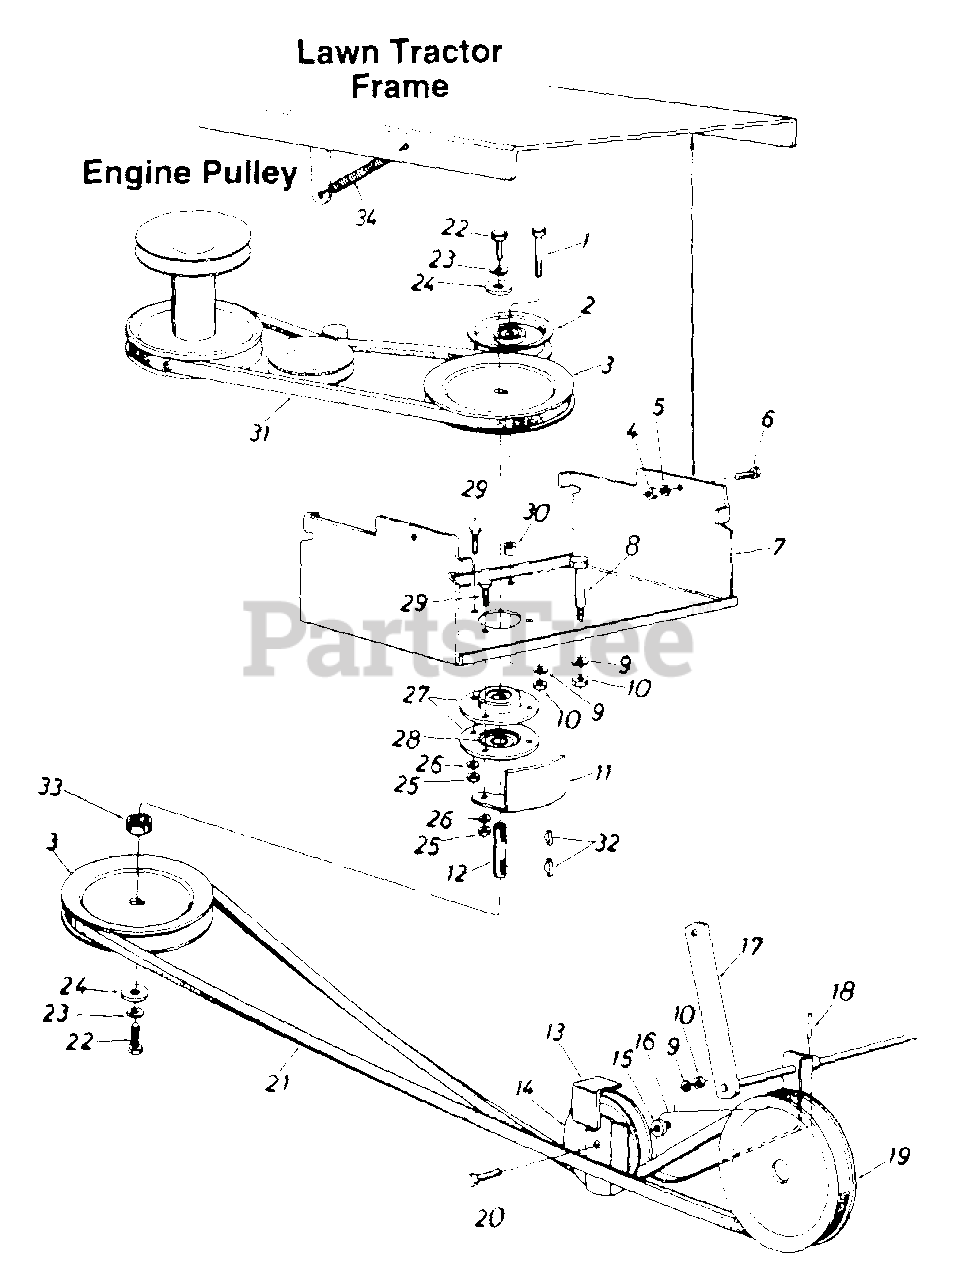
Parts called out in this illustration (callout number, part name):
1	Hex Bolt 3/8-16 x 2" Lg.
2	Fl-Idler w/Flanges 3-3/4" O.D.
3	5/8" "V"-Pulley.79" I.D. x.65" 0 D.
4	Hex Nut 3/8-24 Thd.
5	L-Wash. 3/8" I.D.
6	Hex Bolt 3/8-24 x .88" Lg.
9	L-Wash. 3/8" I.D.
10	Hex Nut 3/8-16 Thd.
13	Belt Separator Plate
14	Fl-Idler w/Flanges 3.25"
15	Fl-Wash..406" I.D. x 1.25"
18	Spring Pin Roll 3/16" Dia.
19	5/8" V-Pulley 1.50" I.D x 6.5" O.D.
20	Hex Bolt 3/8-16 x 1.75" Lg.
21	"V"-Belt
22	Hex Bolt 5/16-18 x 88" Lg. Spec.
23	L-Wash. 5/16" I.D.
24	Fl-Wash..344" I.D. x 1.125"
25	Hex Nut 5/16-18 Thd.
26	L-Wash. 5/16" I.D.
27	Bearing Housing 1.85" I.D.
28	Ball Bearing 1.85" O.D.
29	Hex Sems Bolt 5/16-18 x .75"
30	Spacer
31	Belt
32	Hi-Pro Key 3/16" x 5/8"
33	Spacer .66" I.D. x 1" O.D.
34	Extension Spring
